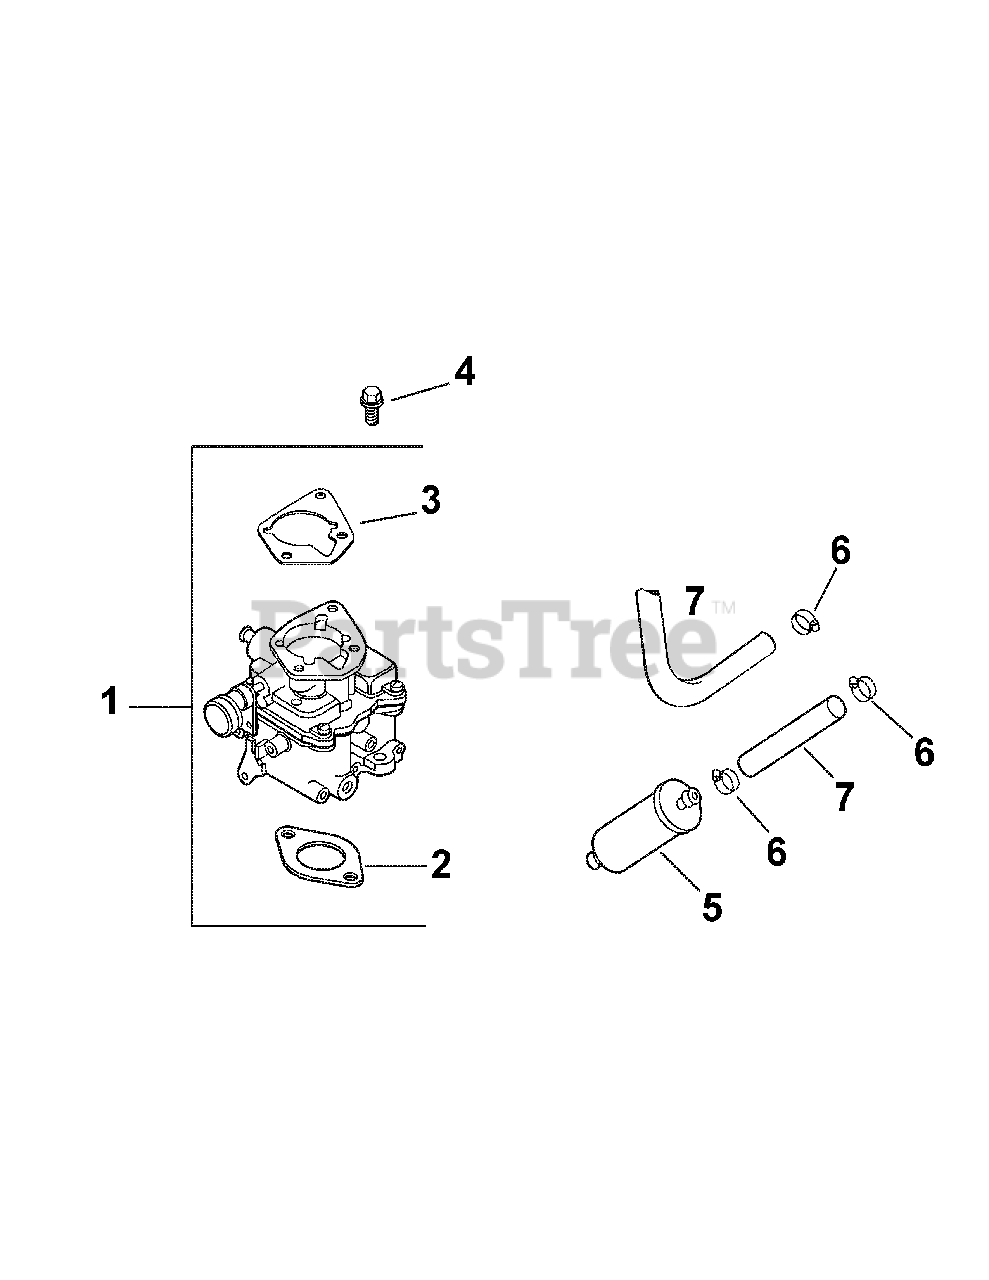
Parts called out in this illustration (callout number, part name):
1	Kit, carb w/gasket
2	Gasket, air cleaner base
3	Gasket, carburetor
4	Screw, hex flange M6x1.0x25
5	Filter, fuel
6	Clamp, hose
7	Line, fuel 24" - cut to length
